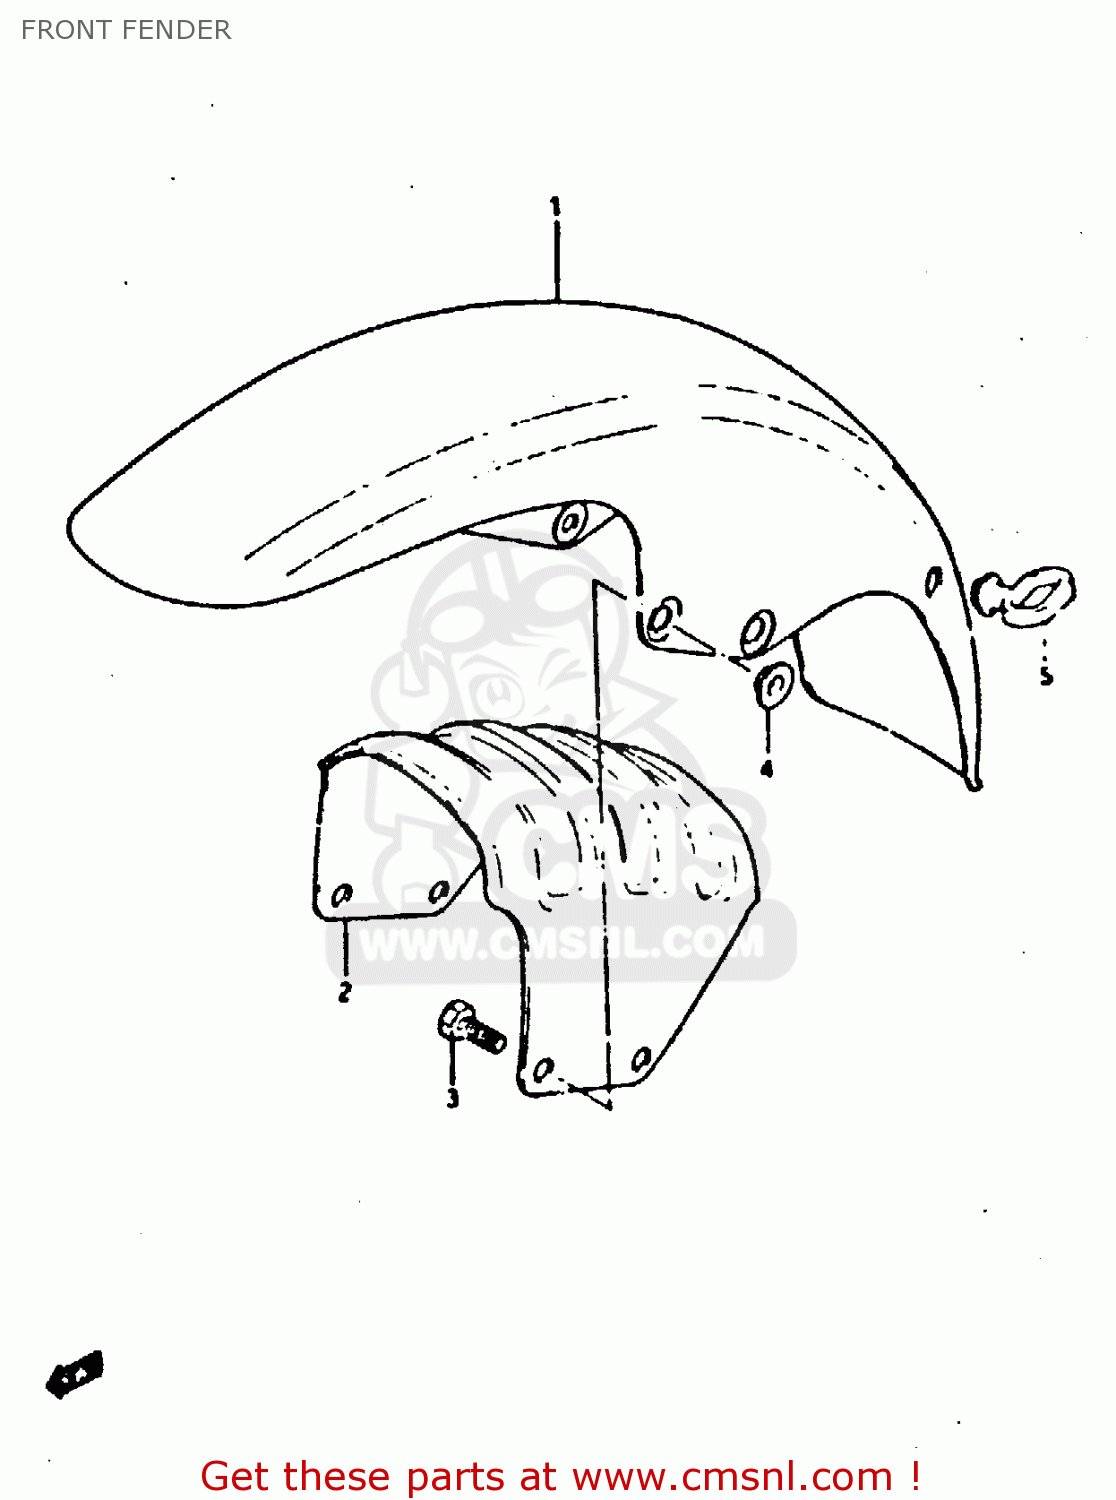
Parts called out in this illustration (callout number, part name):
1	FENDER,FRONT
2	BRACE,FRONT FENDER
3	BOLT 8X16
4	WASHER
5	GUIDE,CABLE
